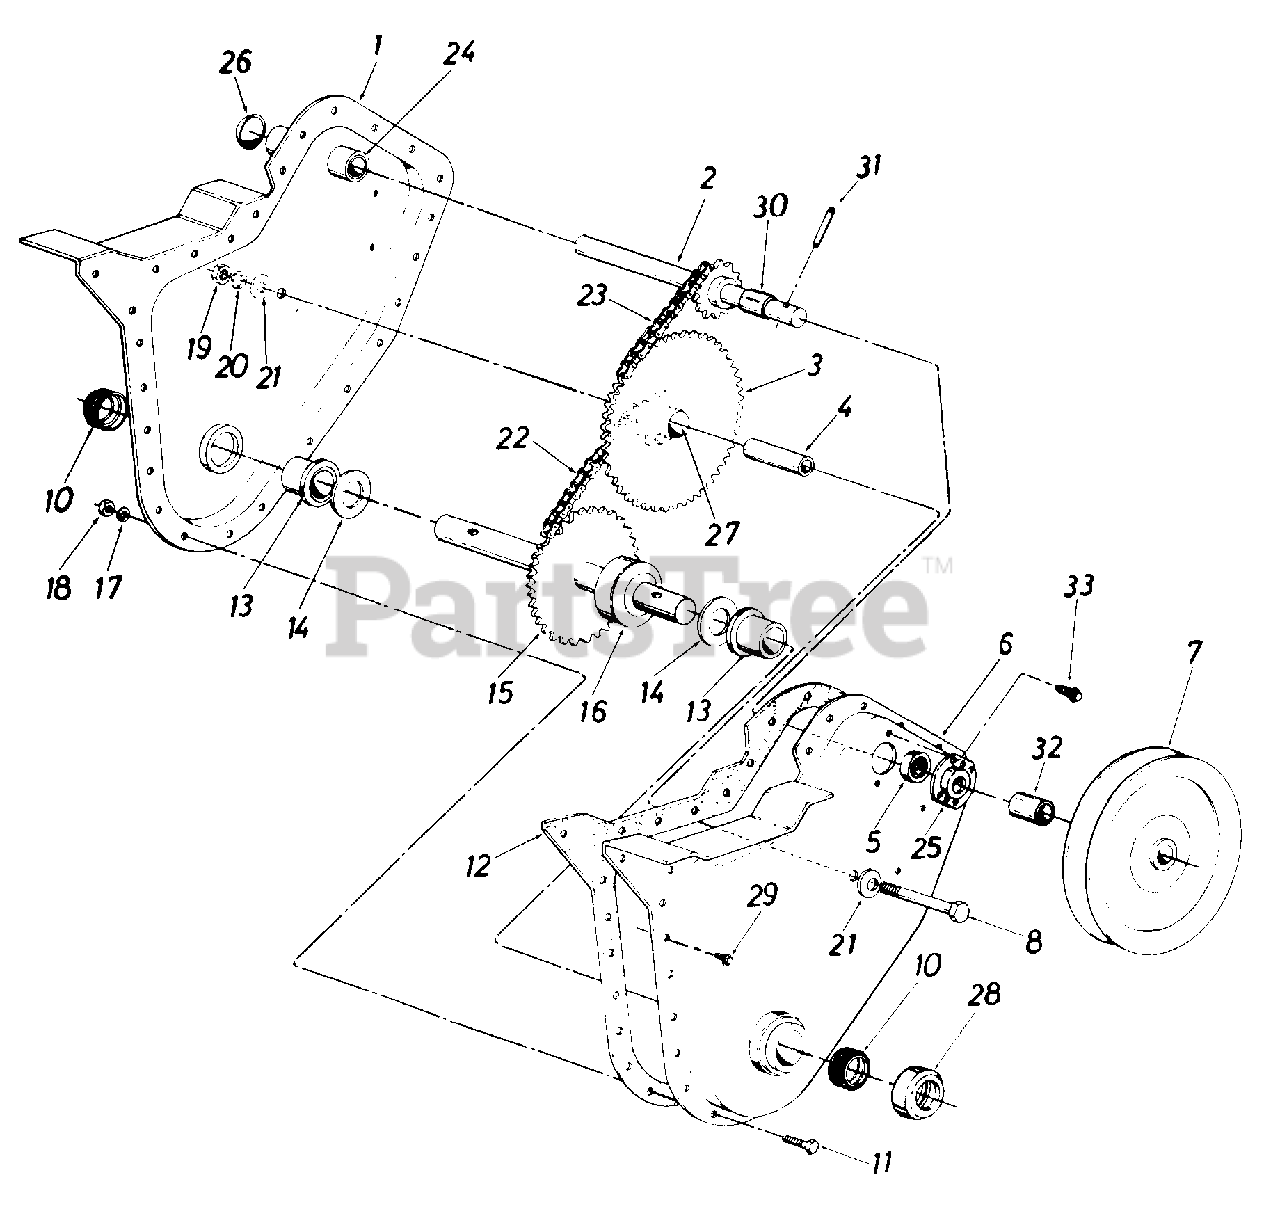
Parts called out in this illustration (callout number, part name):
1	Chain Case Ass'y. R.H.
2	Input Shaft Ass'y.
3	Hub and Sprocket Ass'y.
4	Bearing Inner Race
5	Ball Bearing
6	Chain Case Ass'y. L.H.
7	Pulley Chain Case 5-1/2 x 1/2
8	Hex Bolt 3/8-24 x 2.50" Lg.
11	Hex Bolt 1/4-28 x .625" Lg.
12	Gasket
13	Flange Brg. .879 I.D.
14	Fl-Wash. .88 I.D. x 1.50 O.D. x .030
15	Tine Shaft Ass'y.
16	Spacer 7/8" I.D. x 2.0" O.D. x.68" Lg.
17	L-Wash. 1/4" I.D.
18	Hex Nut 1/4-28 Thd.
19	Hex Ins. L-Nut 3/8-24 Thd.
20	L-Wash. 3/8" I.D.
21	Bell-Wash. .406 I.D. x 1.130 O.D.
22	Chain #420 .50" Pitch x 38 Links
23	Chain #35 .375" Pitch x 50 Links
24	Bearing .62" I.D. x .813 O.D. x 1.31
25	Bearing Housing
26	Expansion Plug 13/16" Dia.
27	Bearing
28	Dust Cap
29	Hex Wash. Hd. Self-Tap Scr. 1/4-20 x .50" Lg.
30	Spacer.630" I.D. x .77" O.D. x.38" Lg.
31	Spring Pin Spiral 1/4" Dia. x 1-1/2" Lg.
32	Spacer .647 x 1 25"
33	Hex Wash. Hd. Self-Tap Scr. 1/4-20 X .38" Lg.
